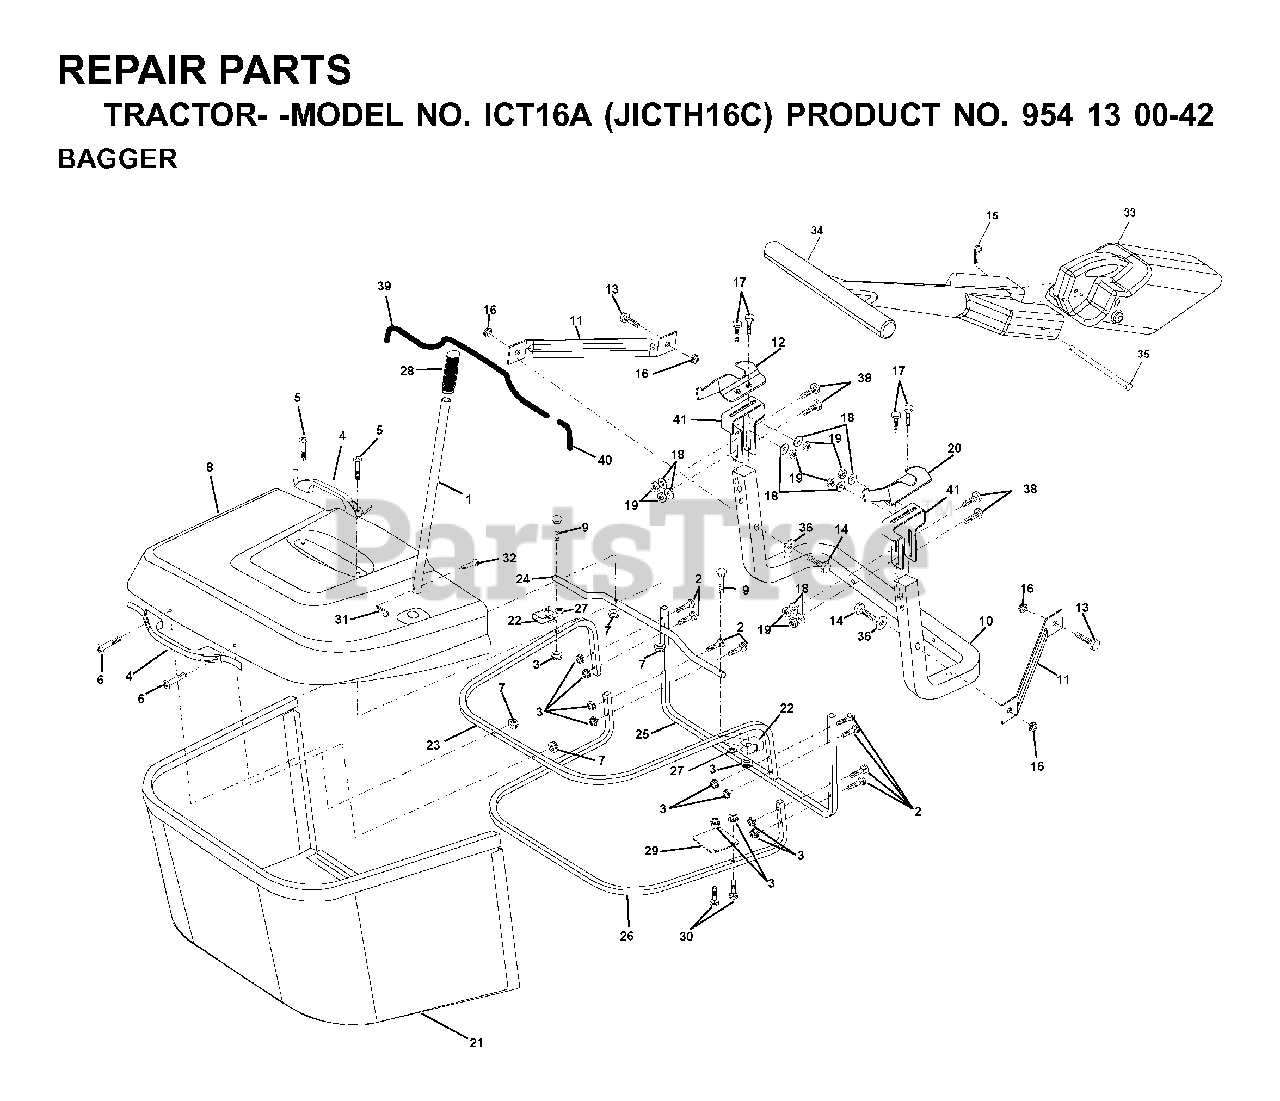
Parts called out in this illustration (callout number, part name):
1	TUBE HANDLE
3	NUT T
5	SCREW.PAN.HEAD
10	TUBE
11	BRACKET
13	BOLT
15	RETAINER-SPRNG RB
16	NUT LOCK FLG 3/8-16 UNC
17	BOLT
18	WASHER M
19	NUT.71038.31-18.HEX.NYLOCK
20	BRACKET
21	BAG
22	BRACKET
23	TUBE
24	TUBE
26	TUBE
28	GRIP.HANDLE.BLACK
31	RETAINER M
32	RIVET,DRILLED
33	MULCH PLUG, CTH150
35	PIN
36	WASHER
38	BOLT.5/16-18X2.5
39	TRIM
40	TRIM
41	BRKT, BAGGER
